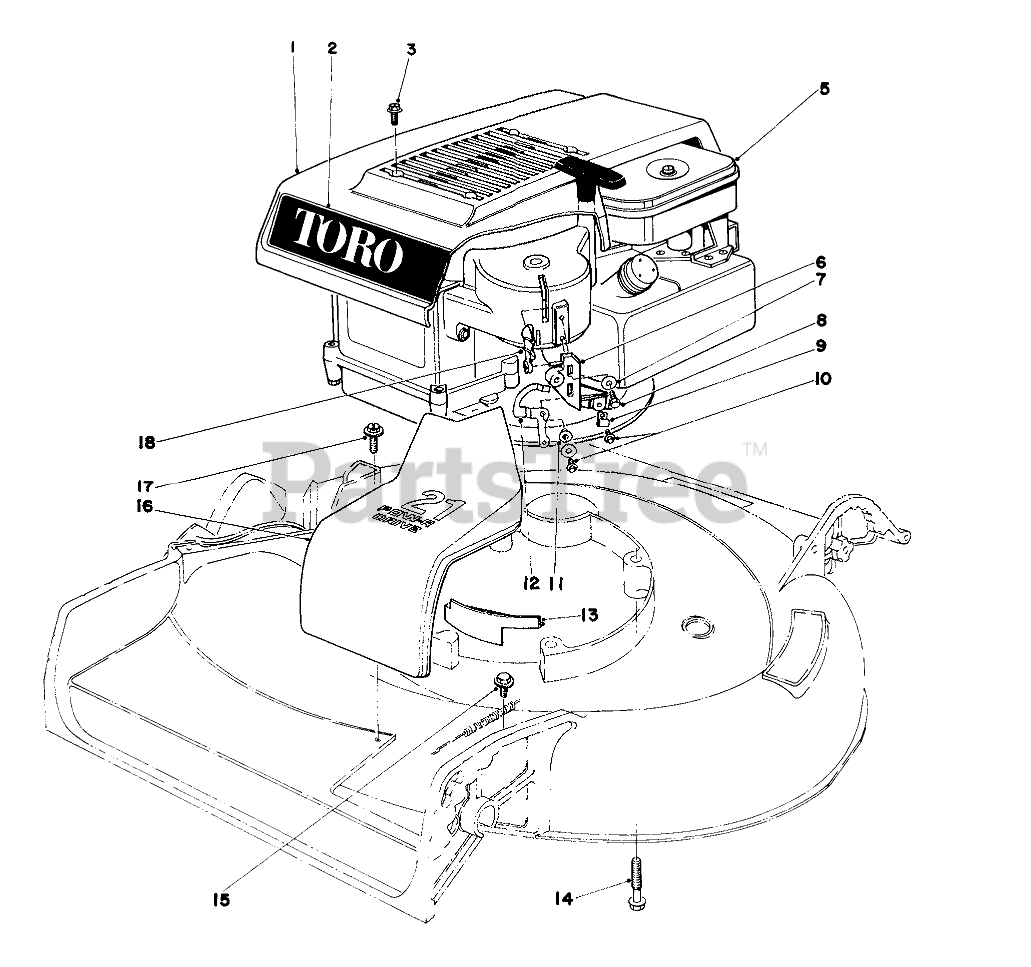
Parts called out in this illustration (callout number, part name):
1	SHROUD
2	Decal-Toro
3	8X1/2 SELF TAP SCREW
5	Engine
6	CABLE & PIVOT BLOCK
7	WASHER-FLAT
8	SCREW-SHWH
9	CLAMP
10	SCREW-HWHTF
11	BUSHING
12	CAM INTERLOCK
13	HOUSING CAP
14	3/8-16 X 2-3/4 CAPSCR
15	SCREW-HWHTF
16	BELT DRIVE COVER
17	SCREW
18	INTERLOCK LEVER
